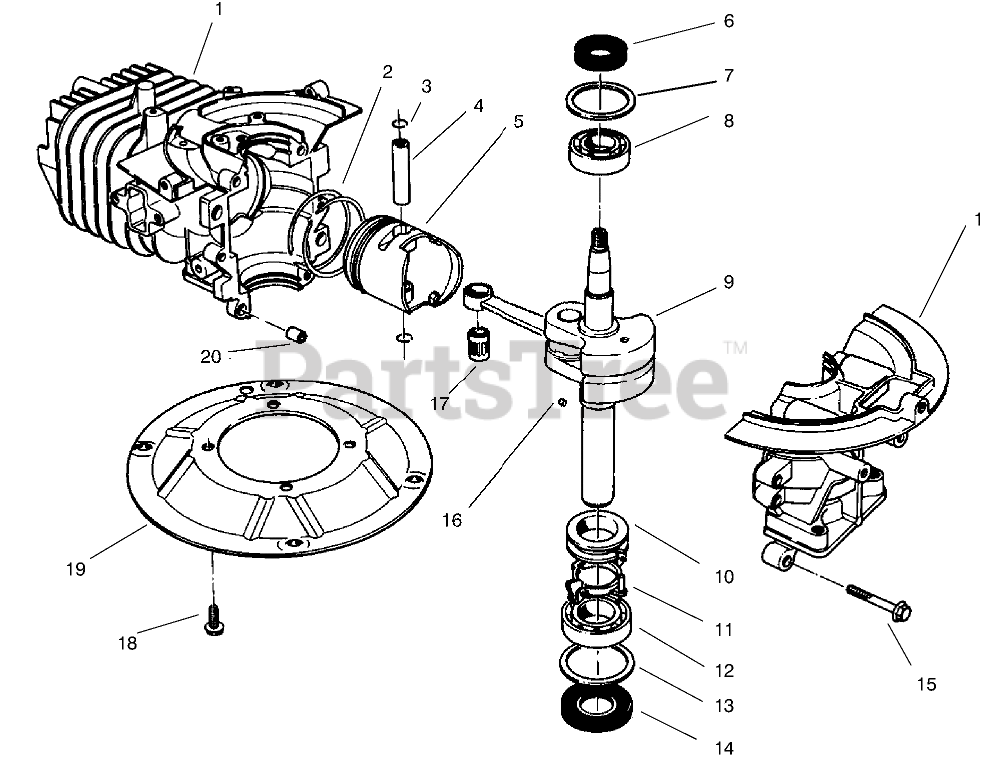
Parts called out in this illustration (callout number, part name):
1	CRANKCASE
1	Crankcase ASM
2	RING SET
4	PIN-PISTON
5	Piston
6	OIL SEAL
7	WASHER-UPPER
8	BEARING-UPPER
9	Pin-Wrist
10	SPACER
11	BRACKET
12	LOWER BRG
13	WASHER-LOWER
14	SEAL-OIL
17	BEARING
19	PLATE-MOUNTING
